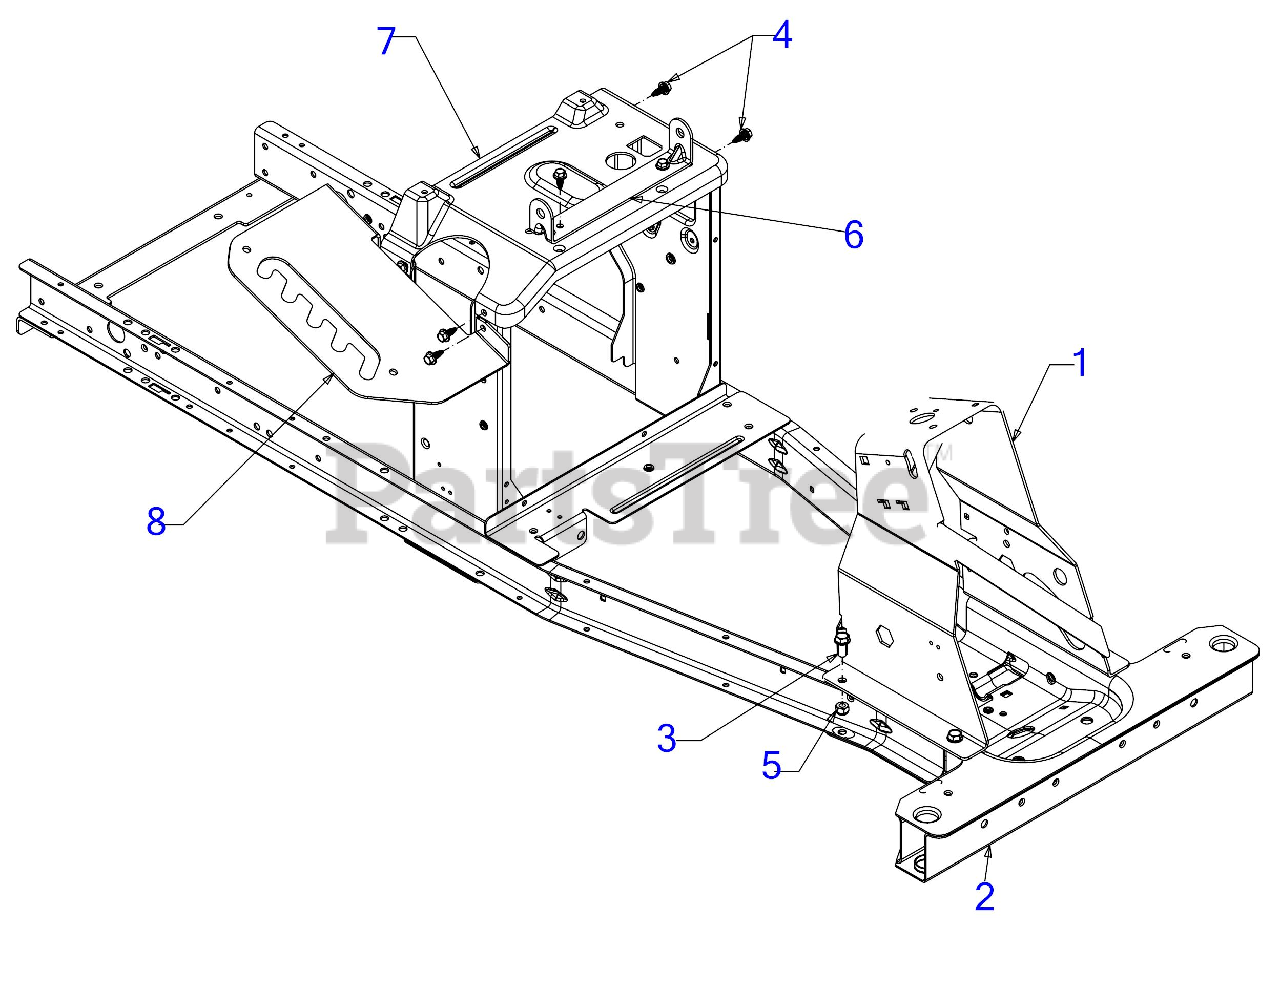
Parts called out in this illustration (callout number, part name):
3	SCREW 5/16-18 x .750 GR8
4	SCREW 1/4-20X.625
5	HEX NUT
6	PIVOT SEAT BRACKET
7	SEAT PAN
